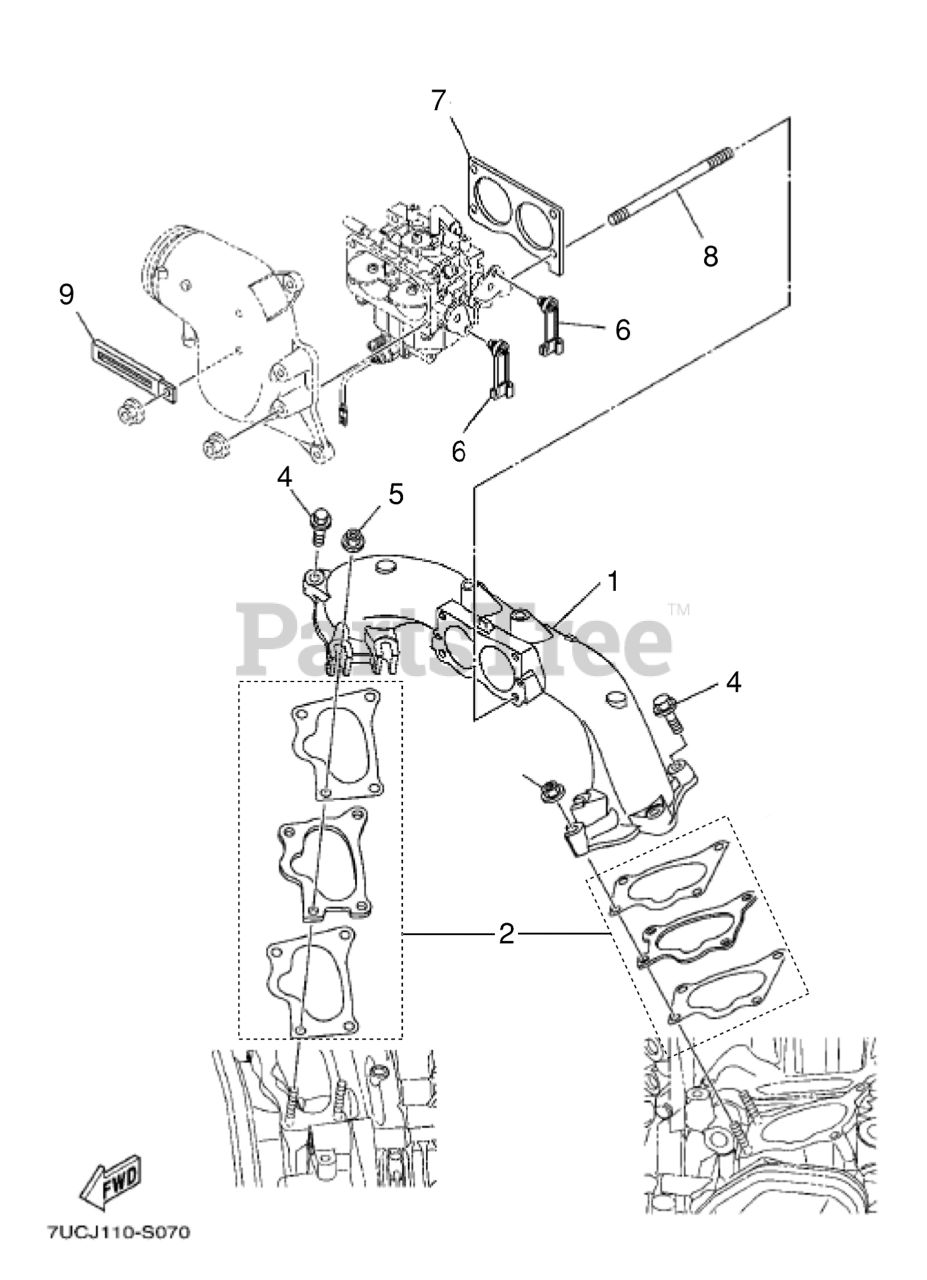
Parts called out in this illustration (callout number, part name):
1	MANIFOLD YAMAHA PN: 7UC-E3585
2	GASKET KIT INTAKE
4	BOLT YAMAHA PN: 95802-06035
5	NUT YAMAHA PN: 95702-06500
6	BOSS ROD END YAMAHA PN: 7UC-G3
7	GASKET MANIFOLD 1 YAMAHA PN: 7
8	BOLT YAMAHA PN: 95622-06700
9	CLAMP YAMAHA PN: 90462-05061
